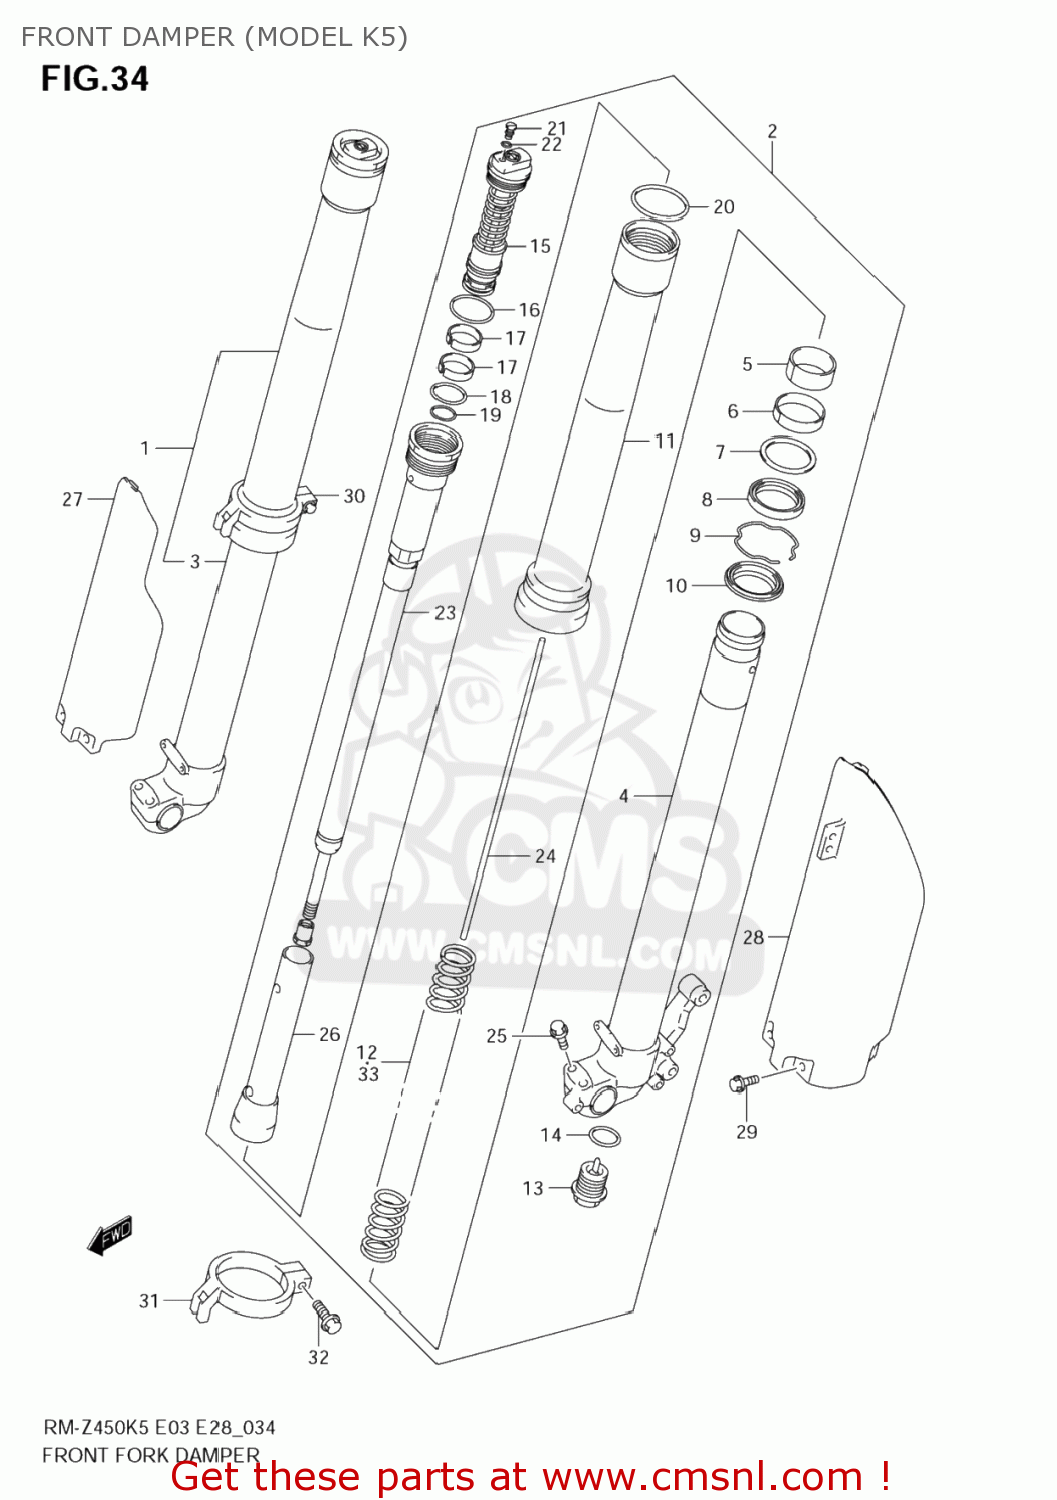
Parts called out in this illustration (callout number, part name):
1	DAMPER ASSY,FR FORK,R
2	DAMPER ASSY,FR FORK,L
3	TUBE,INNER,R
4	TUBE,INNER,L
5	BUSH,SLIDE
6	BUSH,GUIDE
7	SPACER,SEAL
8	SEAL,OIL
9	RING,OIL SEAL STOPPER
10	SEAL,DUST
11	TUBE,OUTER
12	SPRING,FR(K=0.47)
13	BOLT,CTR
14	O RING
15	BOLT,FORK
16	O RING
17	BUSH,FORK BOLT SLIDE
18	O RING
19	O RING
20	O RING
21	BOLT,PLUG
22	O RING,PLUG
23	ROD,DAMPER
24	ROD,PUSH
25	BOLT
26	COLLAR,SPRING
27	PROTECTOR,FR FORK,R
28	PROTECTOR,FR FORK,L
29	BOLT(6X10)
30	GUIDE,PROTECTOR,R
31	GUIDE,PROTECTOR,L
32	BOLT
33	SPRING,FR(K=0.45)
